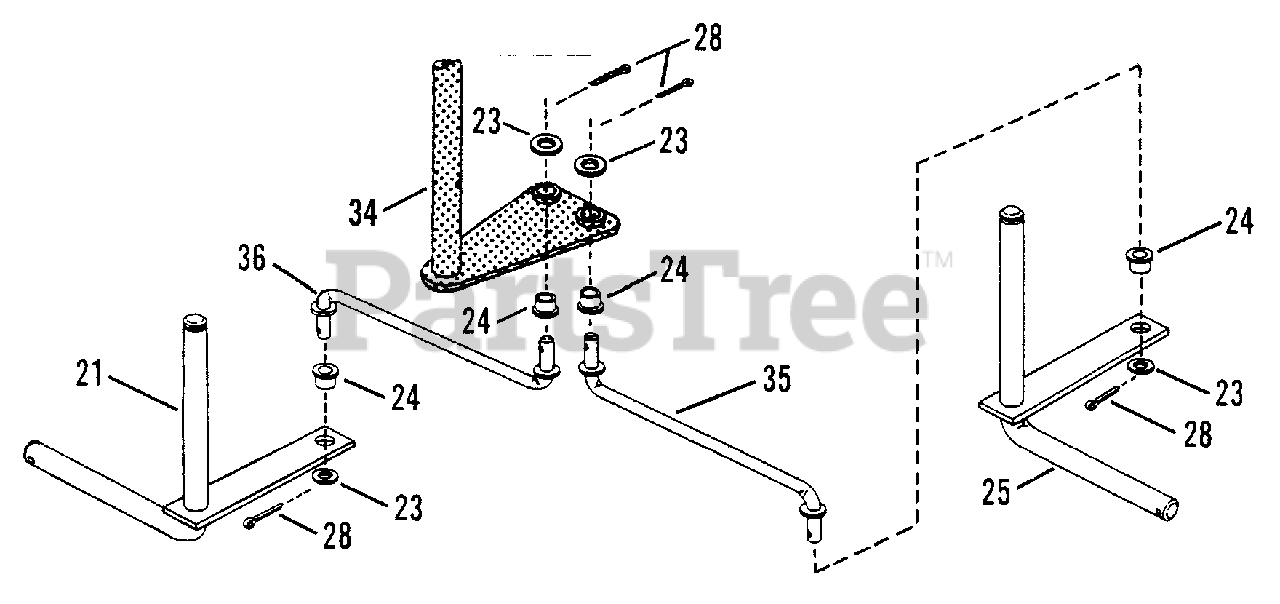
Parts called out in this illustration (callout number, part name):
21	PIN, Narrow King (Right Side)
23	WASHER, 5/16 Split Lock
24	BUSHING
25	PIN, Narrow King (Left Side)
28	PIN, 5/32 x 1" Cotter
34	SHAFT, Steering (Narrow Front End)
35	TIE-ROD, Left Side
36	TIE-ROD, Right Side
